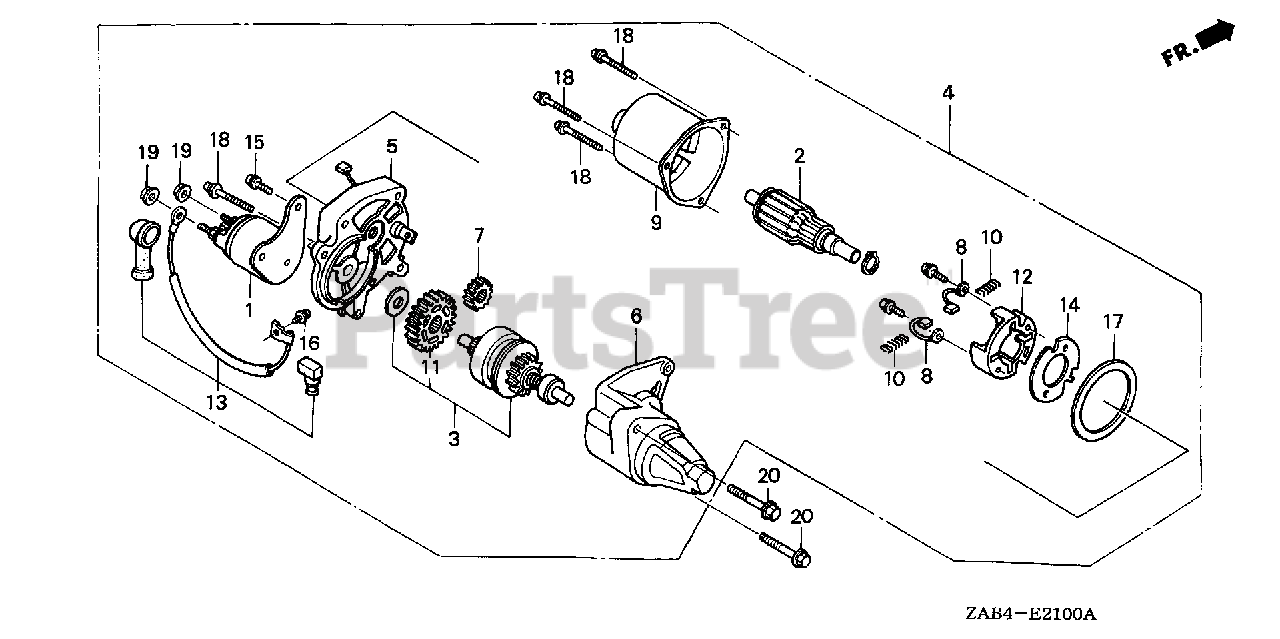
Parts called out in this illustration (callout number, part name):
1	CONTACTOR ASSY.
3	CLUTCH, OVERRUNNING
4	MOTOR UNIT, STARTER
5	BRACKET, CENTER
6	BRACKET, FR.
7	GEAR, DRIVE PINION
10	SPRING, BRUSH RETURN
11	GEAR, REDUCTION
12	HOLDER, BRUSH
13	WIRE, WATER COVER
15	BOLT-WASHER (5X14)
16	SCREW-WASHER (4X6)
18	SCREW-WASHER (5X3)
19	NUT-WASHER (6MM)
20	BOLT, FLANGE (8X35)
